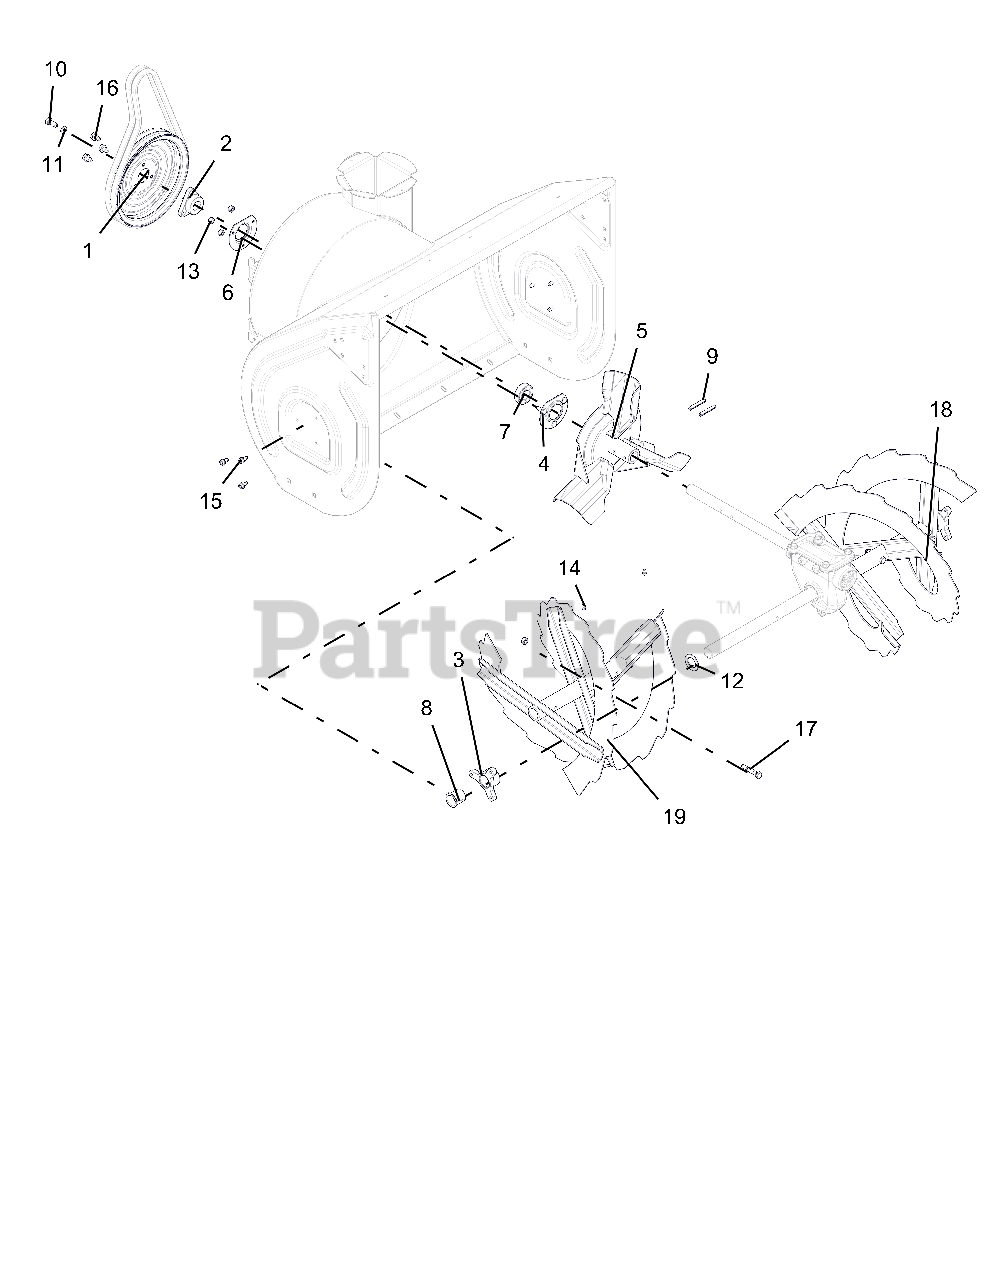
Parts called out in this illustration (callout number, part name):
1	PULLEY, SPIN FORM DUAL GROOVE
2	PULLEY HUB, D-BORE .87 PRO
3	BUSHING, RAKE SHAFT 1"
4	BEARING FLANGE
5	IMPELLER, 3 BLADE-14"
6	BEARING FLANGE
7	BRG-BALL .876X1.75X.50 RSTFP
8	BSHG-FLG SPLIT NYLINER 1.0" HP
9	PIN-ROLL .250X1.75
10	BLT-HEX .31-24X.75 YWZC GR5
11	WSHR-LK .312X.097 HVY YWZC
12	WSHR-FL-STL 1.010X1.505X.062YZ
13	@NUT-LK-CTR .25-20 YWZC
14	ZERK,FITTING .25X.125 DRIVE IN
15	SCR-TAP .25-20X.50 HWH TR YWZ
16	@SCR-TAP .31-18X.50 HWH TR YWZ
17	SHEAR BOLT SERVICE ASSEMBLY
18	RAKE, LH-28"(1 ID X 15.75 OD)
19	RAKE, RH-28"(1 ID X 15.75 OD)
